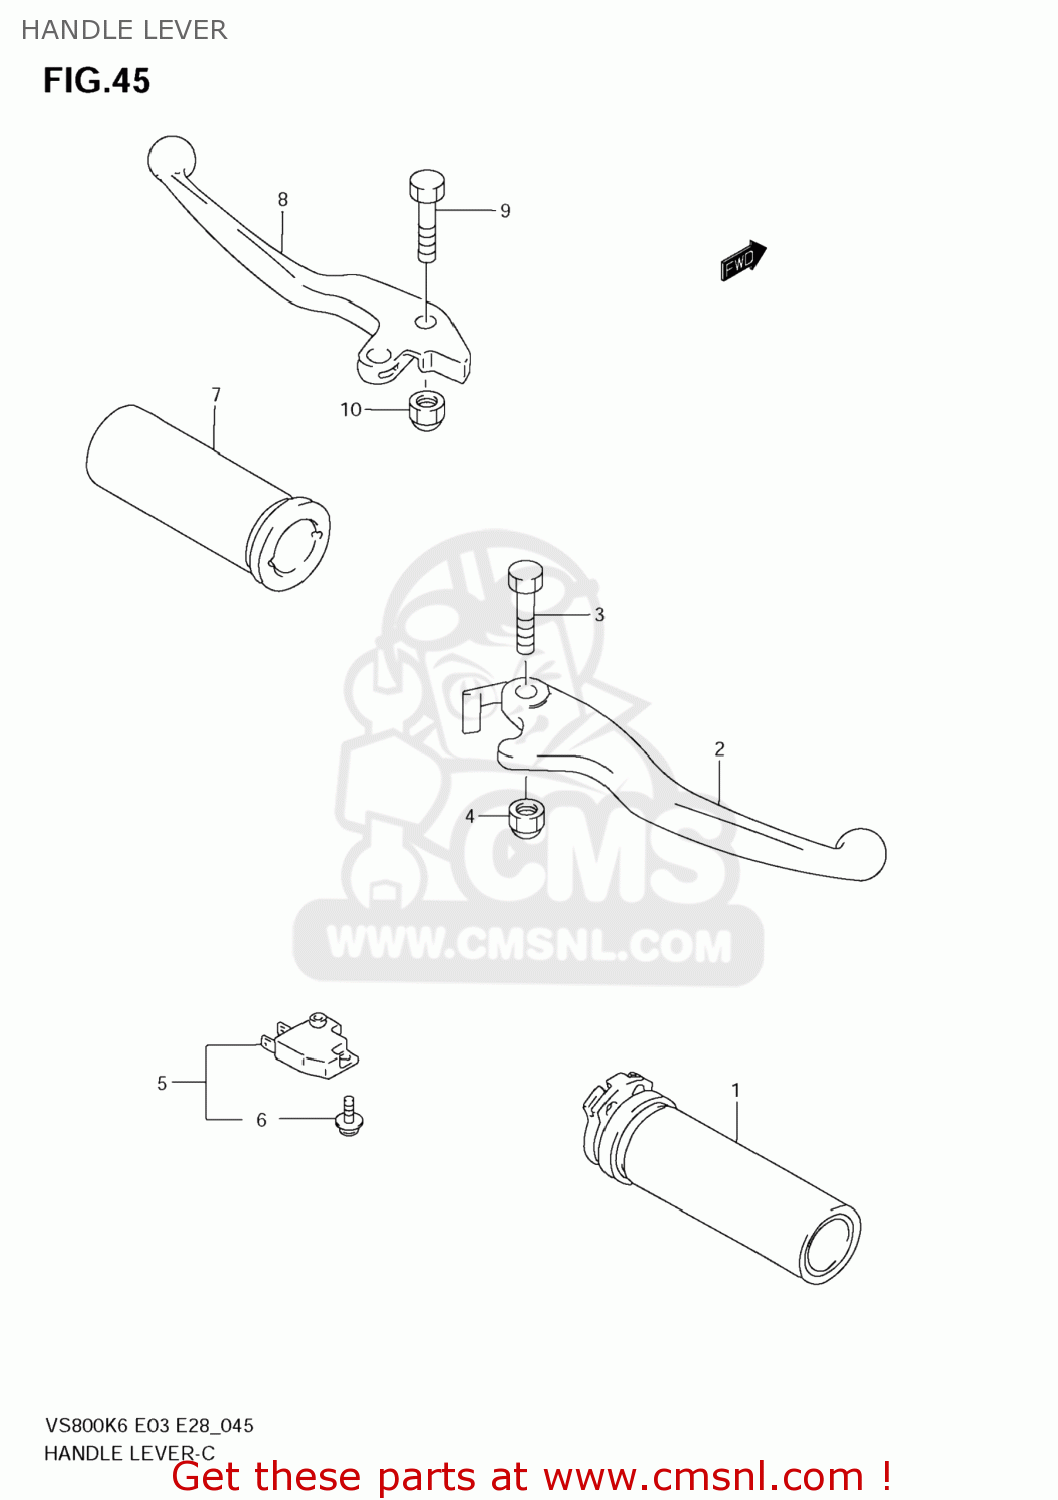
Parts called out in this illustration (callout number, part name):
1	GRIP,THROTTLE
2	LEVER,BRAKE
3	BOLT,LEVER SET
4	NUT
5	SWITCH ASSY,ST
6	SCREW
7	GRIP,L
8	LEVER,CLUTCH (SILVER)
9	BOLT,LEVER SET
10	NUT
